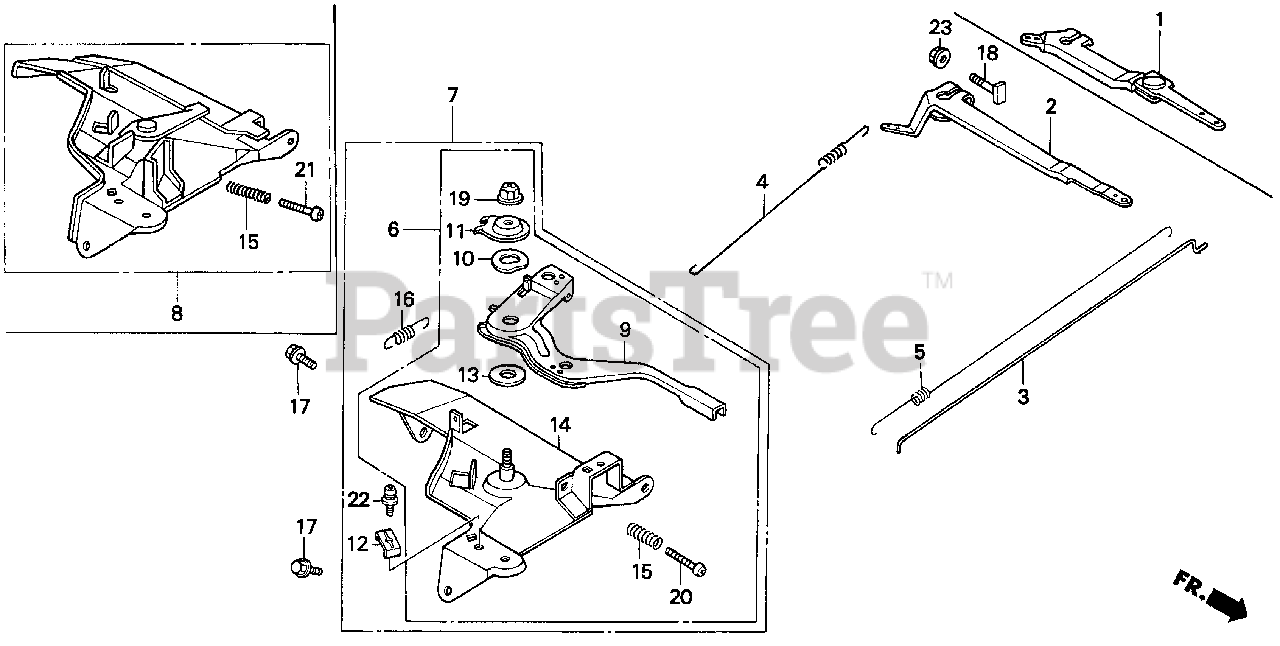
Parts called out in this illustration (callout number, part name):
2	ARM, GOVERNOR
3	ROD, GOVERNOR
4	SPRING, GOVERNOR
5	SPRING, THROTTLE RETURN
7	CONTROL ASSY. (REMOTE)
9	LEVER, CONTROL
10	SPRING, LEVER
11	WASHER, CONTROL LEVER
12	HOLDER, CABLE
13	SPACER, CONTROL LEVER
14	BASE, CONTROL
15	SPRING, CONTROL ADJUSTING
16	SPRING, CABLE RETURN
17	BOLT, FLANGE (6X12) (CT200)
18	BOLT, GOVERNOR ARM
19	NUT, SELF-LOCK (6MM)
20	SCREW, PAN (5X28)
22	SCREW, PAN (5X16)
22	SCREW-WASHER (5X16)
23	NUT, FLANGE (6MM)
